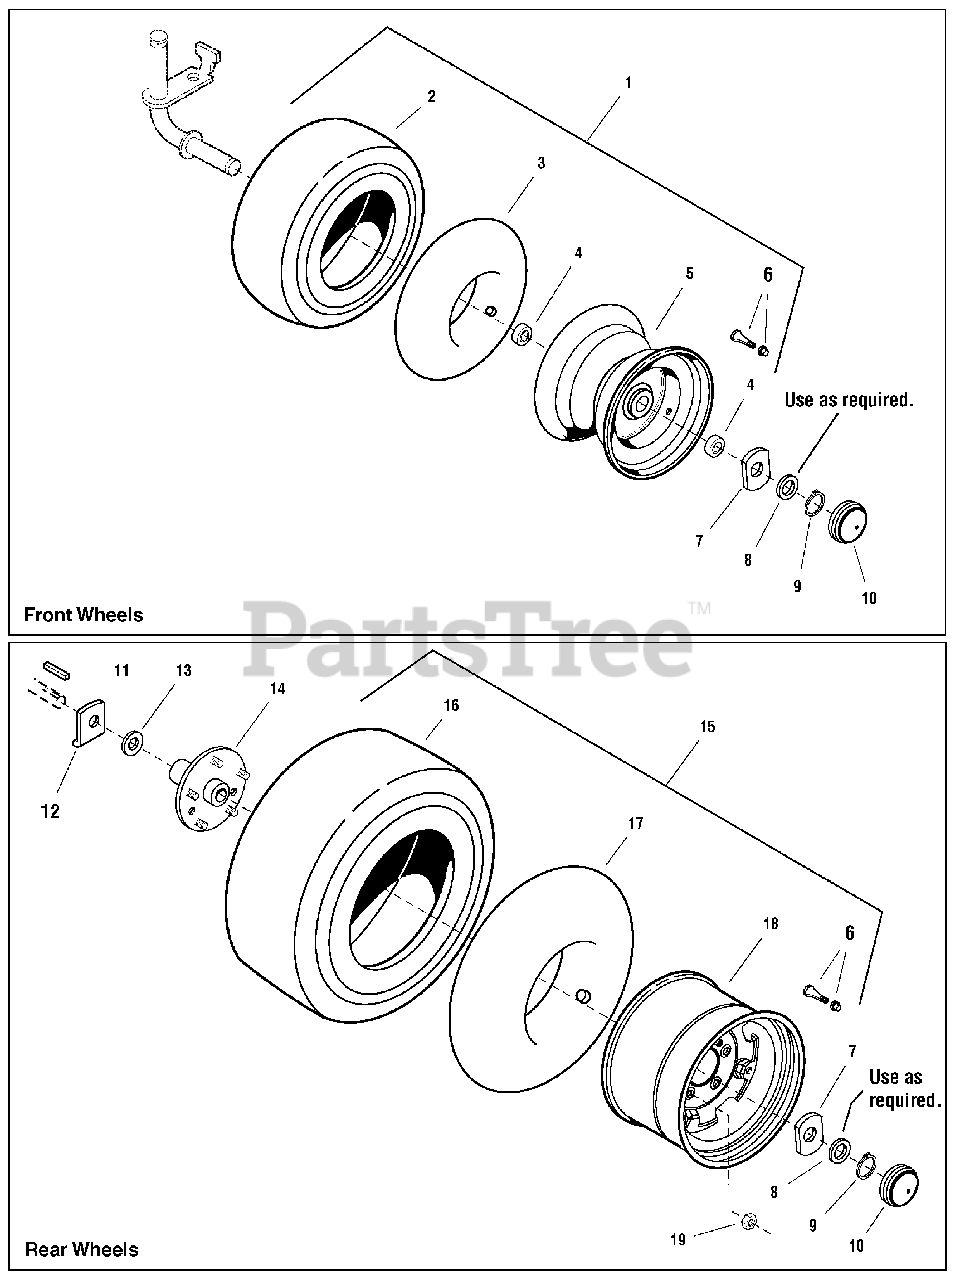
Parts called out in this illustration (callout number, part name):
1	WHEEL & TIRE ASSEMBLY, Front (Includes Ref. 2, 3, 4, 5 & 6)
2	TIRE, 16 x 6-1/2, 8 Super Turf, Front
3	TUBE, Tire 16 x 6 1/2 - 8, Front
4	BEARING, Ball
5	WHEEL, 5-3/8 x 7-15/16, Front
6	VALVE STEM & CAP ASSEMBLY, Air
7	WASHER, Special, 1 x 2-1/2
8	WASHER, 1
9	RING, Retainer
10	CAP, Hub Grey
11	KEY, HI PRO, 1/4 x 2
12	WASHER, Axle Seal "L", 2-1/2 x 2-17/32
14	PLATE & HUB ASSEMBLY, Rear Wheel
15	WHEEL & TIRE ASSEMBLY, Rear 24" (Includes Ref. 6, 16, 17 & 18)
16	TIRE, 24 x 12 - 12 Super Turf, Rear
17	TUBE, Tire 23 x 10 1/2 - 12, Rear
18	WHEEL, 8-1/2 x 12, Rear
19	NUT, Hex, 7/16-20, For Wheel Bolt
